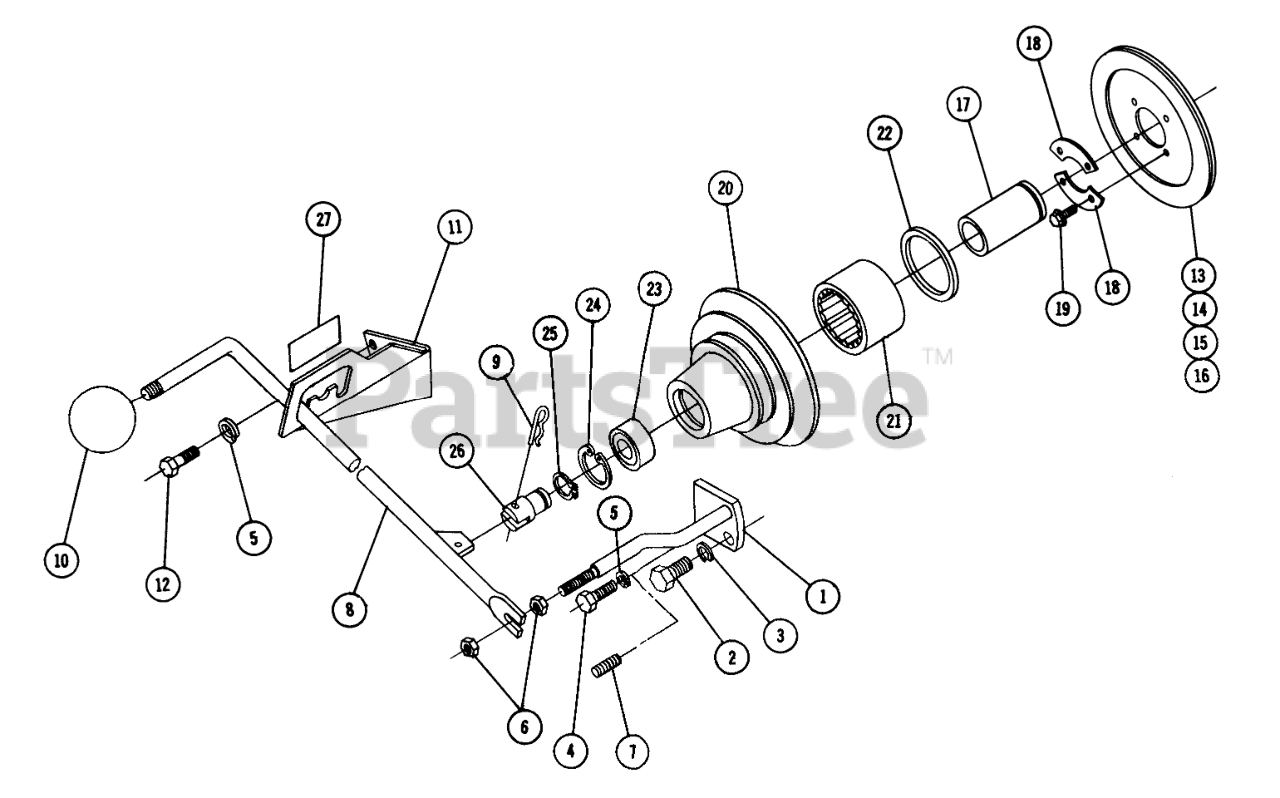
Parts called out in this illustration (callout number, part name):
1	PLATE & ROD ASSEM R
2	Bolt-Hex 7/16 14 x 3/4
3	Lockwasher 3/8
4	Bolt 5/16-18 x
5	Lockwasher
6	3/8-16 E.S.
7	Set Screw 5/16-18 x 3/4 Nylok
8	ROD ASSY
9	Hairpen
10	Knob
11	Bracket
12	Bolt Hex 5/16-18
13	L/A CLUTCHPLATE&FACI
14	Clutch Plate
15	CLUTCH FACING
16	RIVET-BRASS
17	RACE-BEARING
18	RETAINER
19	Bolt, 1/4-20 Whizlock
20	Housing-Clutch
21	Seal
22	SEAL-OIL
23	Bearing
24	Ring-Snap
25	RING-SNAP, EXTERNAL
26	SHAFT
27	DECAL
